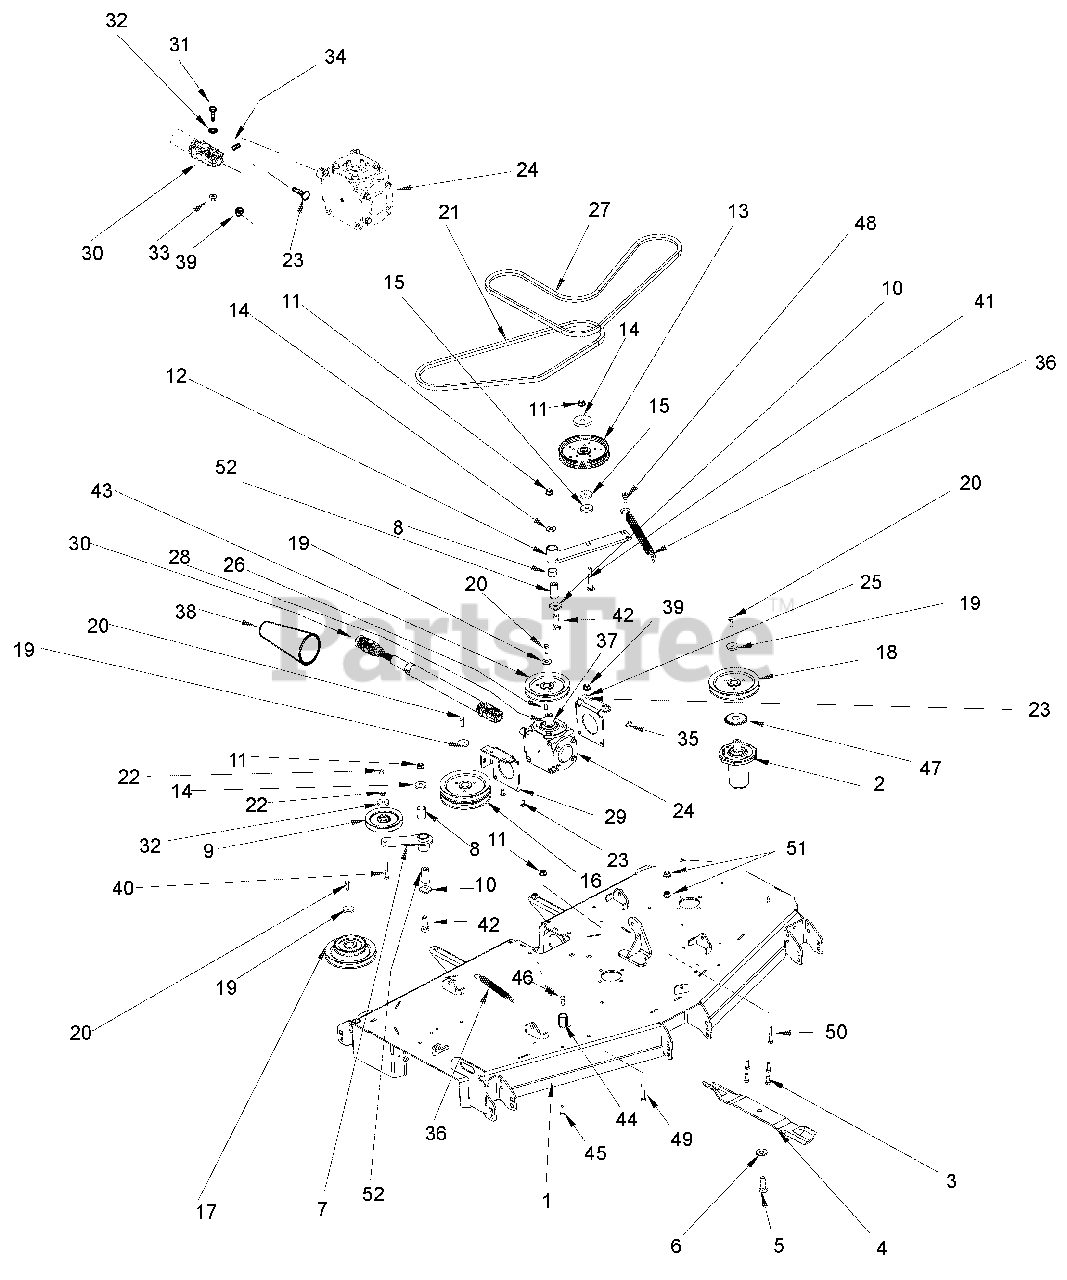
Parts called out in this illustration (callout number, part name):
1	Weldment, 72" Side Discharge Deck
2	Assembly, Spindle
3	Bolt, Hex .38-16 x 1.00 EP30
4	Blade, Mower (24.50")
5	Bolt-Hex .62-18 x 1.75 Grade 8
6	Washer, Bellville .63 x 1.625 x .14
7	Weldment, Idler Pivot Arm
8	Bushing, 1.00 x 1.125 x 1.937
9	Sheave- .38" ID x 5.00" OD V-Idler
10	Washer-Flat, .640 x 1.75 x .250
11	Nut, .50-13 Nyloc Flange
12	Idler Pivot Arm Weldment-Black
13	Idler, Flat-Pulley 6.75 x .510
14	Washer, Flat-Steel .563 x 1.38 x .109
15	Bushing, Spacer .502 x .997 x .50 PM
16	Sheave, Double 1" ID x 8.25" OD
17	Sheave, Double 1.0" ID x 8.25" x 5.25" OD
18	Sheave, Single 1" ID x 8.25" OD
19	Washer, Flat Steel .406 x 1.50 x .245
20	Bolt, Hex .38-16 x 1.00 EP30
21	Belt, B Raw Cogged
22	Nut, Locking-Center .38-16
23	Bolt, Round Head Square Neck .38-16 x 1.00
24	Gear Box, Right Angle 1.05 x 1.0
25	Bracket, Gear Box Mounting
26	Key, Straight .25 x .75 x .25
27	Belt, HB Wrapped
28	Washer, Flat Steel 1.00 x 1.505 x .062
29	Bracket, Gear Box Mounting RH
30	Shaft, PTO Drive Assembly
31	Bolt, Hex .38-16 x 1.175 Grade 5
32	Washer, Flat Steel .406 x .812 x .065
33	Nut, Top-Lock Flange .38-16
34	Screw, Set .38-16 x .62
35	Bolt, Hex .38-16 x .75 Grade 5
36	Spring, Extension
37	Ring, External Retaining 1.00 x .078
38	Bellow, PTO Shaft
39	Nut, Nylon Locking Flange .38-16
40	Bolt, Hex .38-16 x 2.25 Grade 5
41	Bolt, Roundhead Squareneck .50-13 x 3.00 Grade 5
42	Bolt, Roundhead Squareneck .50-13 x 3.50 Grade 5
43	Sheave, Single 1" I.D. x 6.75 O.D.
44	Nut, Coupling .375-16 x 1.75
45	Bolt, Roundhead Squareneck .38-16 x 1.00 Grade 5
46	Bolt, Hex .38-16 x 1.50
47	Retainer, Grease
48	Bolt, Shoulder Hex .38-16 x .30
49	Bolt, Roundhead Squareneck .50-13 x 1.50
50	Bolt, .38-16 x 1.50
51	Nut, Nylon Locking Flange .38-16
52	Bushing-Spacer .502 x .997 x 2.03
